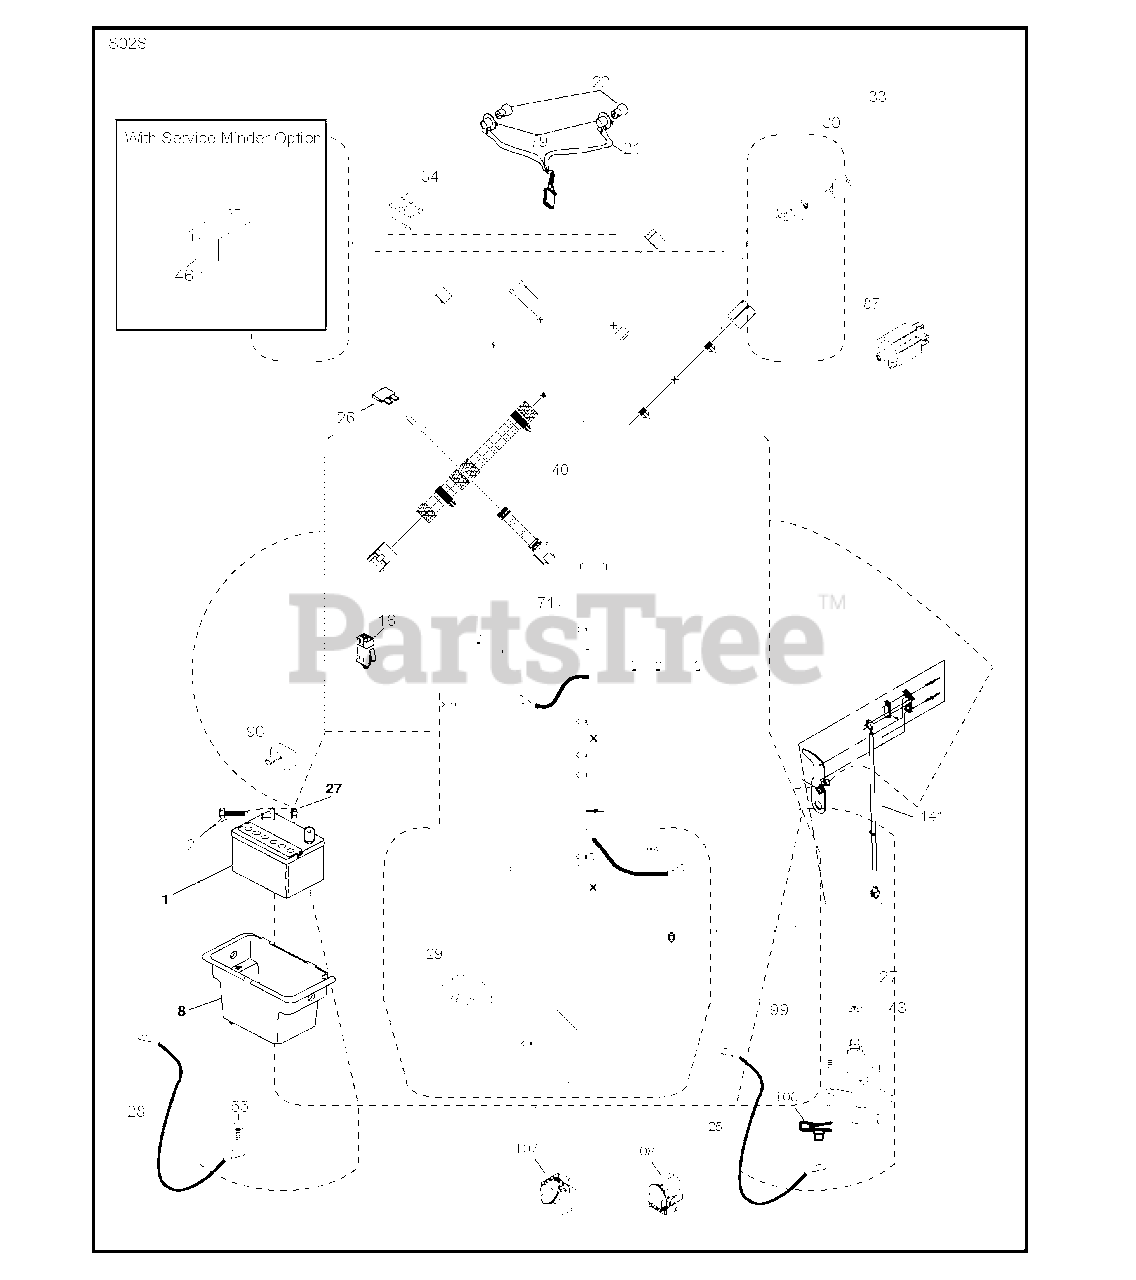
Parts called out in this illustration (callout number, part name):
16	SWITCH INTERLOOK PUSH-IN
21	HARNESS.LIGHT W/4152J BULBS
22	LIGHTBULB
25	CABLE.BATTERY.20.RED.8 AWG
26	FUSE 20AMP
27	NUT
29	SWITCH.SEAT.DELTA.OPC.
30	SWITCH.IGN.DELTA.W.LGH.ROS
33	KEY.CHAIN.BLISTER.PACK.GEN.INT
34	SWITCH LT
43	SOLENOID.W/BRASS.PLUNG
55	SCREW 5/16"
79	BULB HOLDER ASM.
90	COVER, TERMINAL BATTERY
99	SCREW HEXWSHR 1/4-20X3/4
106	1/4-20 U NUT
108	SWITCH.SNAPMOUNT.NC
141	KIT T2.ROS
